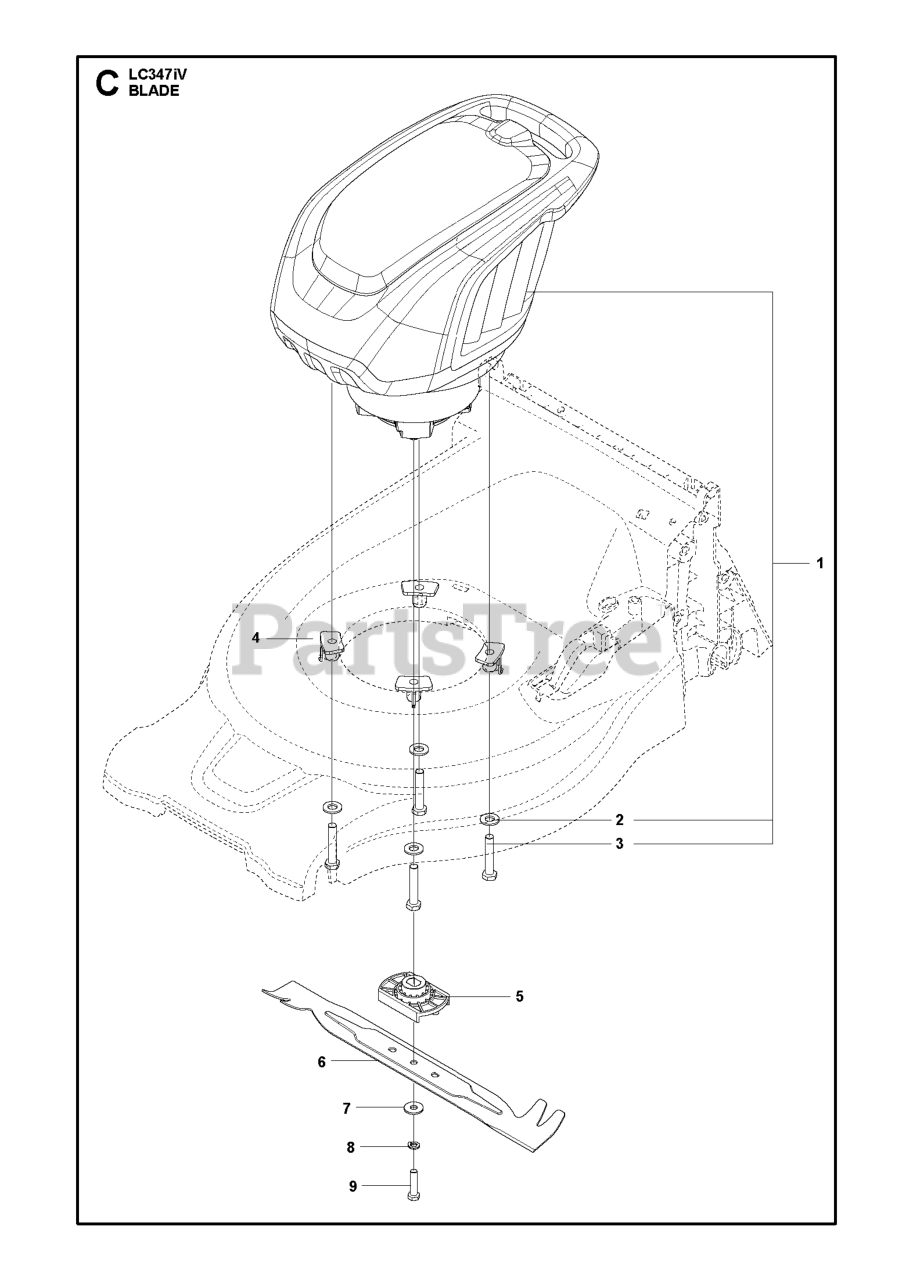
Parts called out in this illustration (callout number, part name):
3	SCREW
5	BLADE SUPPORT TRANSMISSION SYS
7	SPACER
8	SPRING WASHER
9	SCREW
